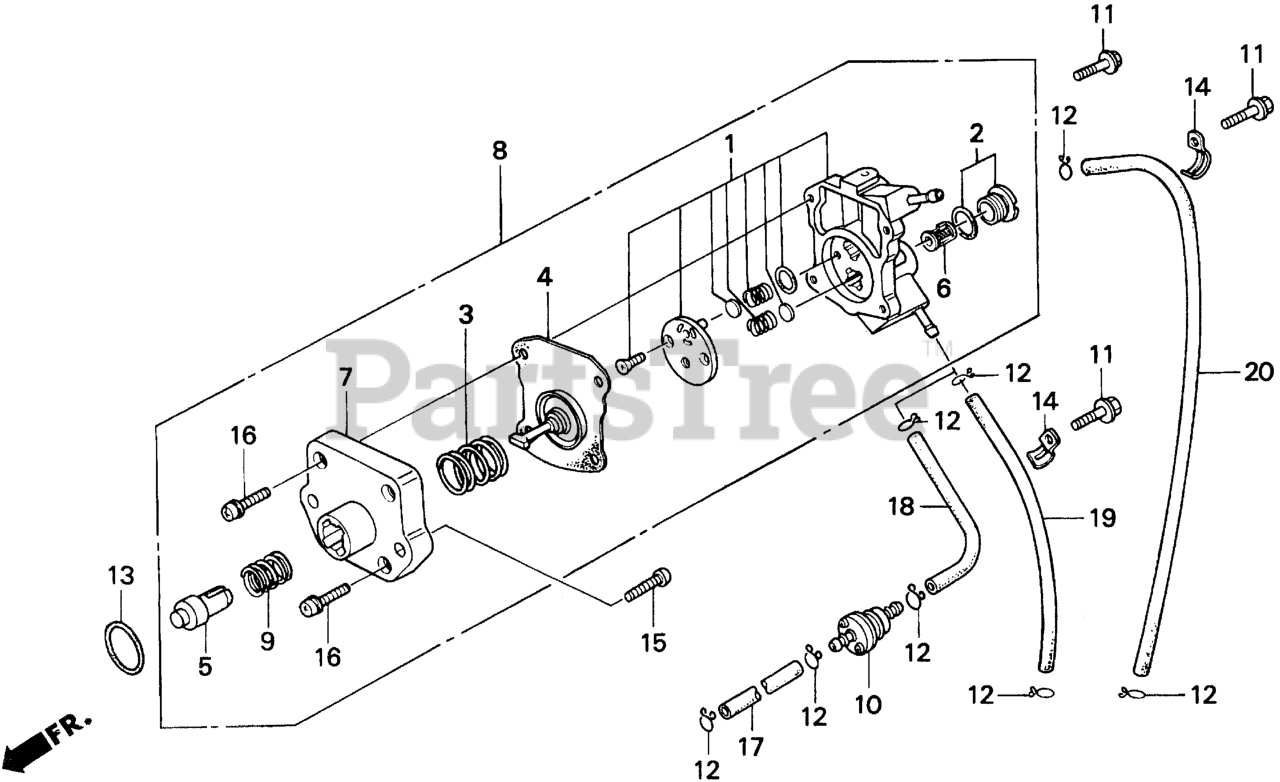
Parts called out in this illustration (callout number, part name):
1	BODY SET, PUMP
2	BOLT SET, HOLDING
3	SPRING, DIAPHRAGM
5	ROD, PUSH
6	SCREEN, FUEL STRAINER
7	BODY (LOWER)
8	PUMP ASSY., FUEL (MSDS)
9	SPRING, PUSH ROD
10	FILTER, FUEL
11	BOLT, FLANGE (6X28)
12	CLIP, TUBE (B8)
13	O-RING (20.8X2.4)
14	CLIP B, CORD
15	SCREW, PAN (6X20)
16	SCREW-WASHER (4X16)
17	BULK HOSE, FUEL (4.5X3000) (Honda Code 5137104). (4.5X140)
18	BULK HOSE, FUEL (4.5X3000) (Honda Code 5137104). (4.5X140)
20	BULK HOSE, FUEL (4.5X3000) (Honda Code 5137104). (4.5X140)
